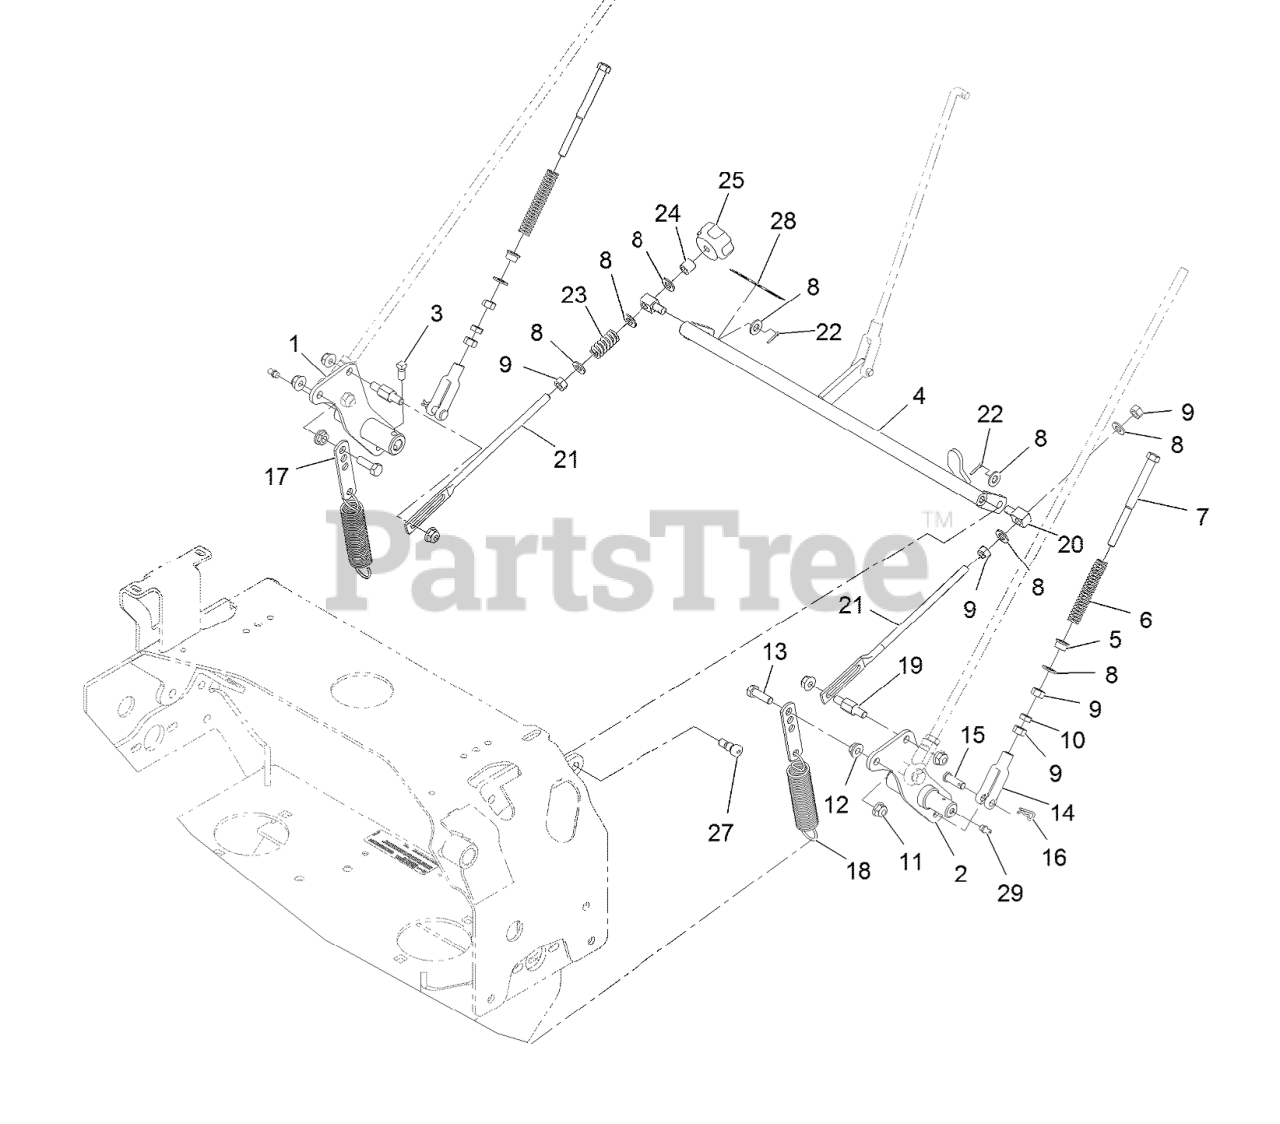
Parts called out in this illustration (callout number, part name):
1	WELD, MOTION CONTROL, RT
2	WELD, MOTION CONTROL, LT
3	SCREW-SET
4	WELD, SPEED CONTROL
5	BUSHING-FLANGED
6	SPRING,COMPRESSION (NEUT)
7	BOLT-RETURN, NEUTRAL
8	WASHER-PLAIN
9	NUT-HEX
10	NUT-JAM
11	NUT-HF, NI
13	SCREW-HH
14	YOKE-ADJUSTABLE
15	PIN-CLEVIS
16	PIN-COTTER
17	TAB-SPRING, EXTENSION
18	SPRING-EXTENSION
19	PIN, MOTION CONTROL
20	SWIVEL-ADJUSTABLE, SHORT
21	LINK-CONTROL, SPEED
22	PIN-COTTER
23	SPRING-COMPRESSION
25	KNOB-TRACKING
27	SCREW-HSH
28	DECAL-TRACKING ADJUSTMENT
29	FITTING-GREASE
